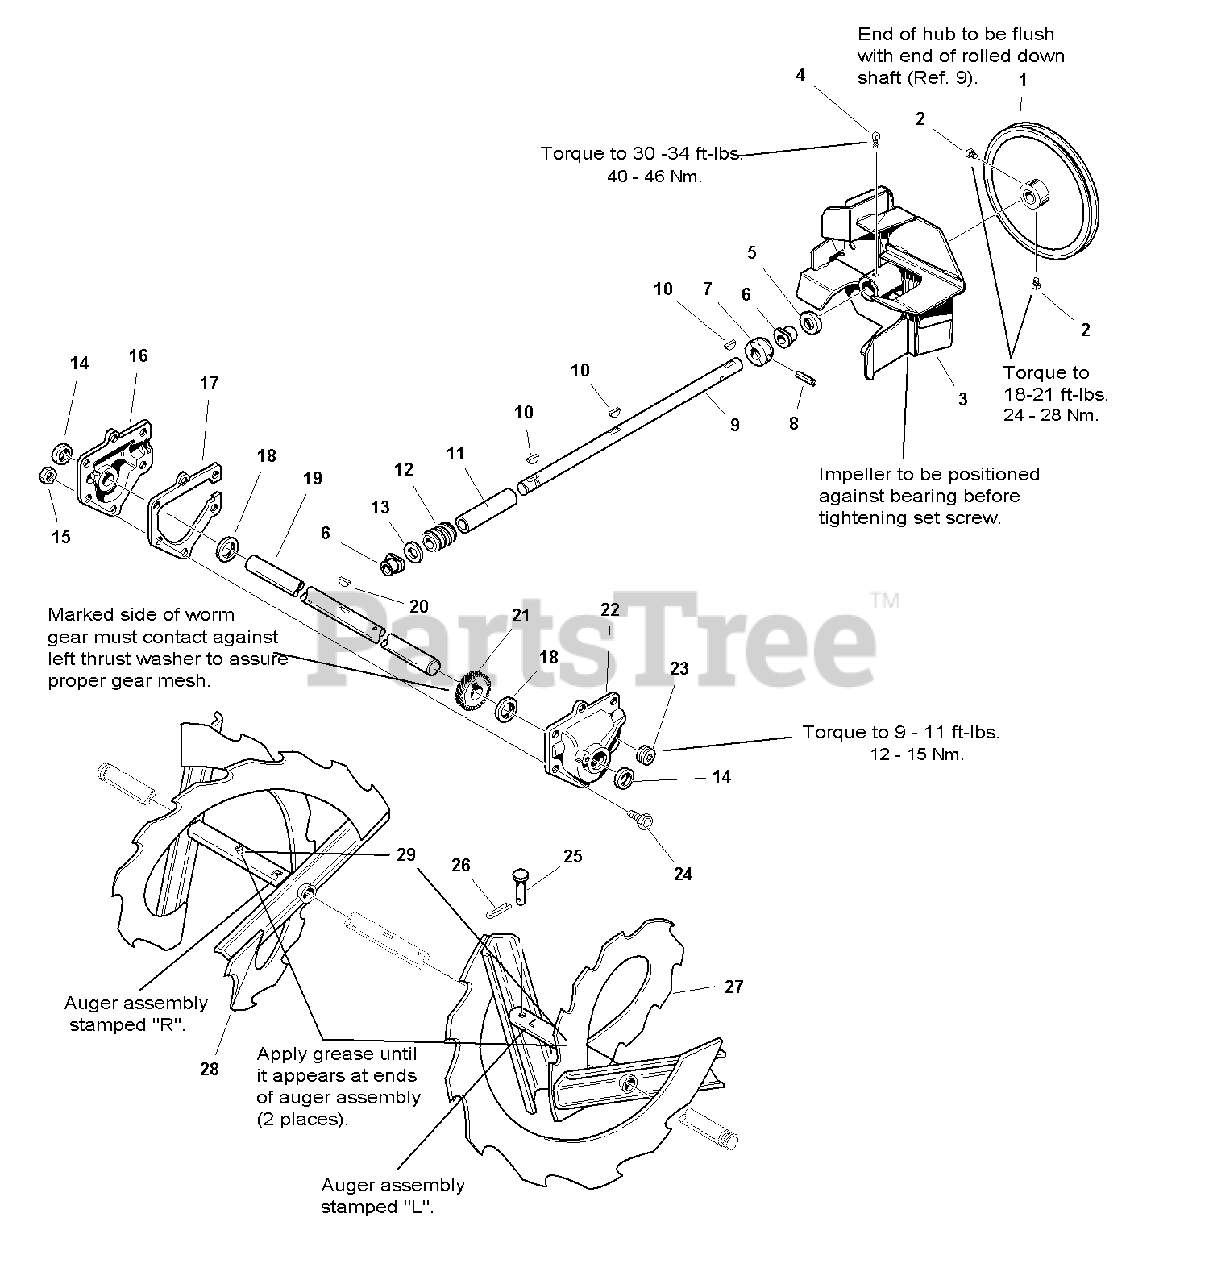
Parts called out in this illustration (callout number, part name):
1	PULLEY, Auger Input
2	SETSCREW, Square Head, 5/16-18 x 1/2
3	IMPELLER ASSEMBLY
4	SETSCREW, Square Head, 3/8-16x 1/2
6	BUSHING, Flange
7	COLLAR, Thrust
8	PIN, Drivelok, 3/16 x 1-1/2
9	SHAFT, Worm
10	KEY, Woodruff, 3/16 x 5/8
12	GEAR, Rolled Worm
13	WASHER, Thrust
15	LOCKNUT, Hex, 1/4-20
16	CASE, Gear, RH
18	WASHER, Thrust
19	SHAFT, Auger
20	KEY, Woodruff, 1/4 x 3/4
21	GEAR, Worm
22	CASE, Gear, LH
23	PLUG, Pipe, Tapered, 1/8
24	CAPSCREW, Hex Head, 1/4-20 x 2 1/4
25	PIN, Shear
26	PIN, Cotter, 3/32 x 3/4
27	AUGER ASSEMBLY, LH, 28"
28	AUGER ASSEMBLY, RH, 28"
29	FITTING, Lube, 1/4
30	CAPSCREW, Hex Head, 1/4-20 x 2 1/2
